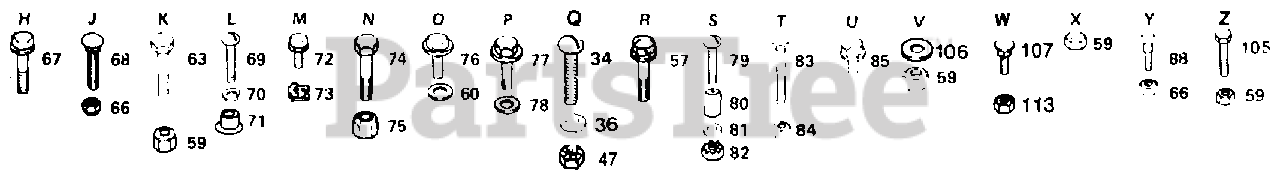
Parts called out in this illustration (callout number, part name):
34	SCREW
36	WASHER
57	SCREW
60	WASHER PM
63	BOLT
68	BOLT
69	SCREW
70	LOCKWASHER
71	WELDNUT
73	"""J"" FASTENER LT"
74	BOLT T
76	SCREW
77	SCREW
78	WASHER
79	SCREW
80	SPACER LT
81	WASHER
83	BOLT
84	NUT GTV
85	SCREW LT
106	WASHER
107	BOLT
113	NUT T
